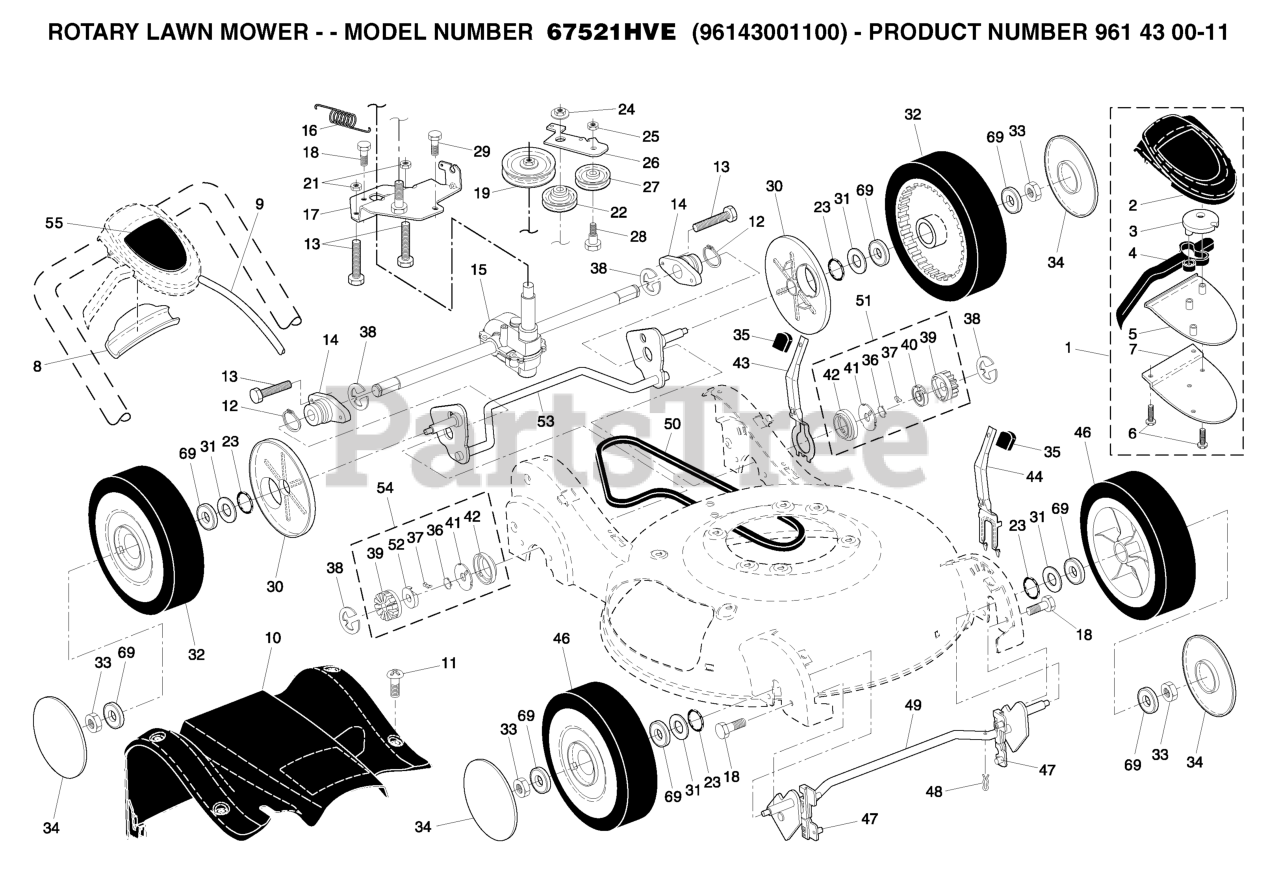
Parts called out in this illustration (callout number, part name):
1	CONTROL.DR.HV.RWGD.GRY/BLU
2	CASE.TOP.GRAY
3	PULLEY.CAM.DRIVE.CONTROL.HV
4	LEVER
5	CASE BOTTOM
6	SCREW, PHILLIPS HEAD 10 X 5/8
7	BRACKET, DRIVE CONTROL
8	EZ WALK SNAP COVER PLATE
9	ASM.CABLE.
11	SCREW
12	RETAINING RING (2 2)(3 2)
13	RP SCREW
14	BEARING.SUPPORT.ASSEM
15	TRANSMISSION.21.HI-VAC.EZ
16	SPRING.RETURN
17	BRKT.TRANSMISSION.HV.E
21	NUT
22	PULLEY.IDLER.V-BELT
23	O-RING
24	NUT
25	NUT.CENTERLOCK.5/16-
26	ARM.IDLER.BZP
27	IDLER PULLEY
28	SHOULDER BOLT
29	SCREW 14-20 X 5/8
30	DUST COVER, WHEEL
31	WASHER.FLAT.1/2
32	WHEEL.9X2.25.PR.JUNG.BLK
33	HEX FLANGE LOCKNT
34	RB HUBCAP.3-SPOKE.SILVER
35	KNOB.SELECTOR.SPRG.H-GRY (2 2)
36	SPRING, TORSION
37	PAWL.DRIVE.21.EZ-WALK
38	E-RING 7/16 RE
39	GEAR, PINION
40	RETAINER.DRIVE.21.EZ-WALK.LT
41	DISC.DRIVE.21.EZ-WALK
42	SEAL.PINION
43	LEVER, SELECTOR, HEIGHT, REAR
44	LEVER, SELECTOR, HEIGHT, FRONT
46	WHEEL.9X2.25.LP.JUNG.BLACK
47	BUSHING.FRONT.TORQUE.SHAFT
48	SPRING RETAINER
49	SHAFT FRONT
50	BELT.DRIVE.EZ.WALK.HI-VAC
51	PINION ASSY, LH
52	RETAINER, DRIVE, RH
53	AXLE.ASM.REAR.TORQUE.BZP
54	PINION ASSY, RH
69	BEARING.8".WHEEL
